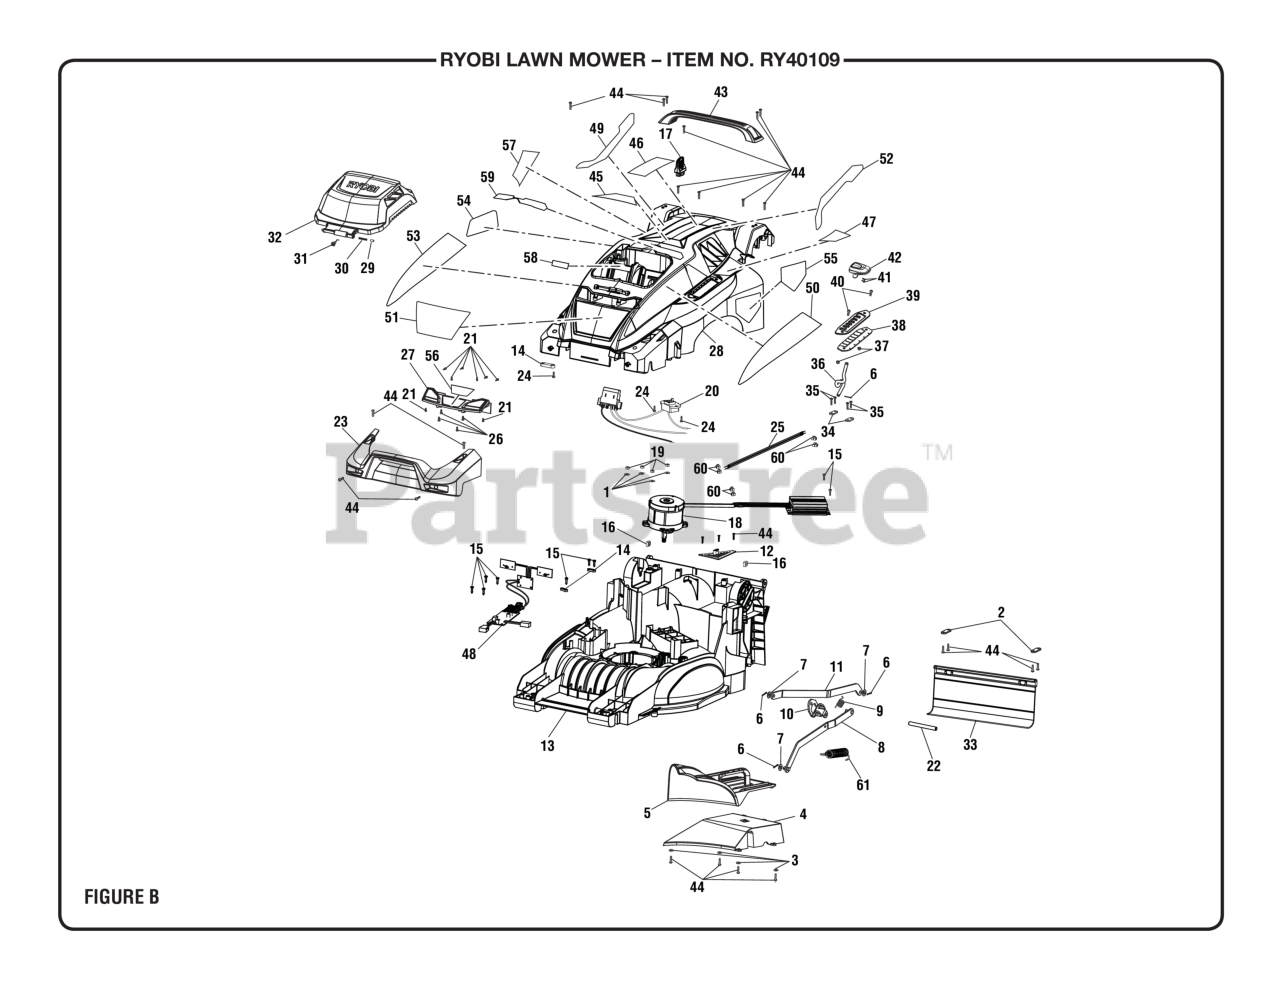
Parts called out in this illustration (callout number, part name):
1	Washer (ID6.2 x OD15 x 0.08t)
2	Axle Pressure Plate
3	Washer (ID4.5 x OD10 x 1t)
5	Mulching Plug
6	Cotter PinÏ? (2.5)
7	Washer (ID8.4 x OD18 x 1t)
8	Front Lift Rod
9	Torsion Spring (Height Adjustment)
10	Height Adjustment Bracket
11	Rear Lift Rod
12	Transmission Cover
14	Wire Press Plate
15	Screw (M4 x 16 mm, T20 Torx Pan Hd.).
16	Square Nut (M8)
17	Start Key
18	Motor and Controller Assembly
19	Lock Nut (M6)
20	Contact Plate Holder Assembly
21	Screw (M3 x 8 mm, Pan Hd., Pan Hd)
22	Axle (Height Adjustment)
23	Front Bumper
24	Screw (M4.2 x 12 mm, T20 Torx Pan Hd.)
25	Inner Wire Connector
26	Screw (M4 x 10 mm, T20 Torx Pan Hd.)
27	Light Assembly w/Label
28	Deck Cover Assembly (Inc. Key Nos. 45-47, 49-55 & 57-59)
29	Battery Door Axle
30	Compression Spring
31	Battery Cover Spring
32	Battery Cover
34	Pressure Plate (Height Adjustment)
35	Screw (M4 x 18 mm, T20 Torx Pan Hd.)
36	Lever Arm
37	Lock Nut (M5 x 0.8 mm)
38	Shifter Boot
39	Height Adjustment Plate
40	SCREW (M5 x 16 mm SOC. WASHER HD. CAP)
41	Screw (M3 x 9 mm, Flat Hd.)
42	Height Adjustment Handle
43	Carrying Handle
44	Screw (M4 x 20 mm, T20 Torx Pan Hd. S.T.)
45	Danger/Warning Icon Label (English)
46	Bilingual Danger (French/Spanish) & Trilingual Warning (English/French/Spanish) Label
47	Height Adjustment Label
48	Circuit Board w/LED Assembly
49	Stripe Label (Right)
50	Brushless Label (Left)
51	40V Self Propelled Logo Label
52	Stripe Label (Left)
53	Brushless Label (Right)
54	Data Label
55	Danger Label (No Hands/Feet)
56	LED Headlight Label
57	40V Lithium Label
58	On Board Battery Storage Label
59	Start Key Label
60	Terminal Block w/Screw
61	Rentention Spring
